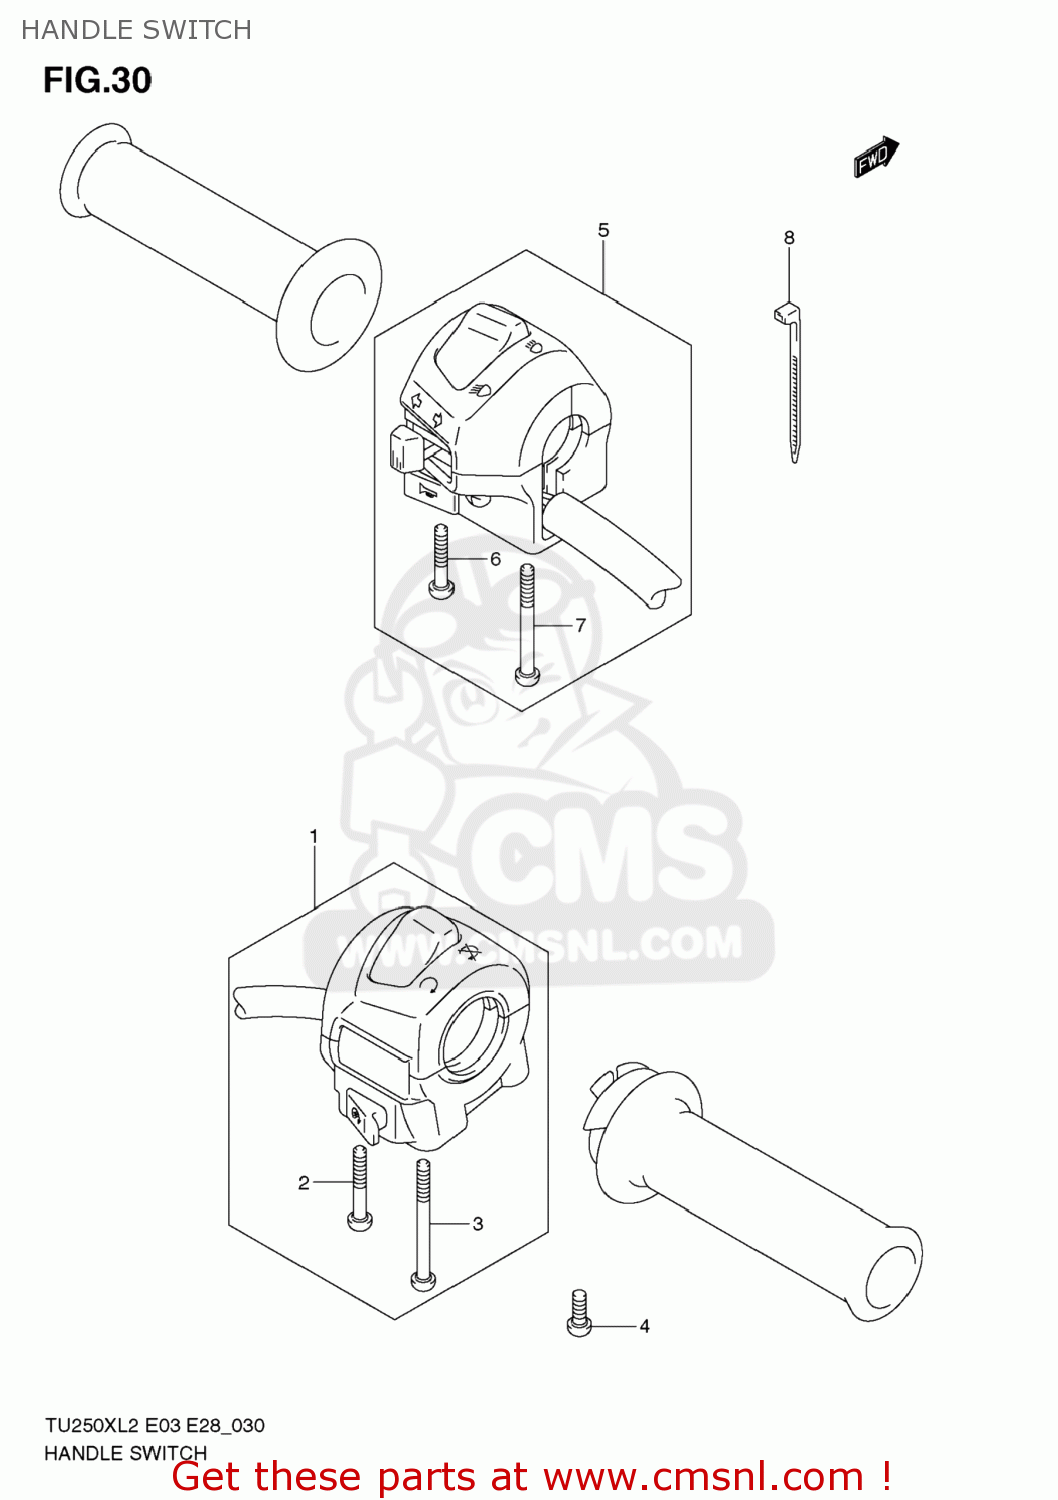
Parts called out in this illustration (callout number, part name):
1	SWITCH ASSY,HA
2	SCREW
3	SCREW
4	SCREW
5	SWITCH ASSY,HANDLE,L
6	SCREW
7	SCREW
8	CLAMP(L:145)
